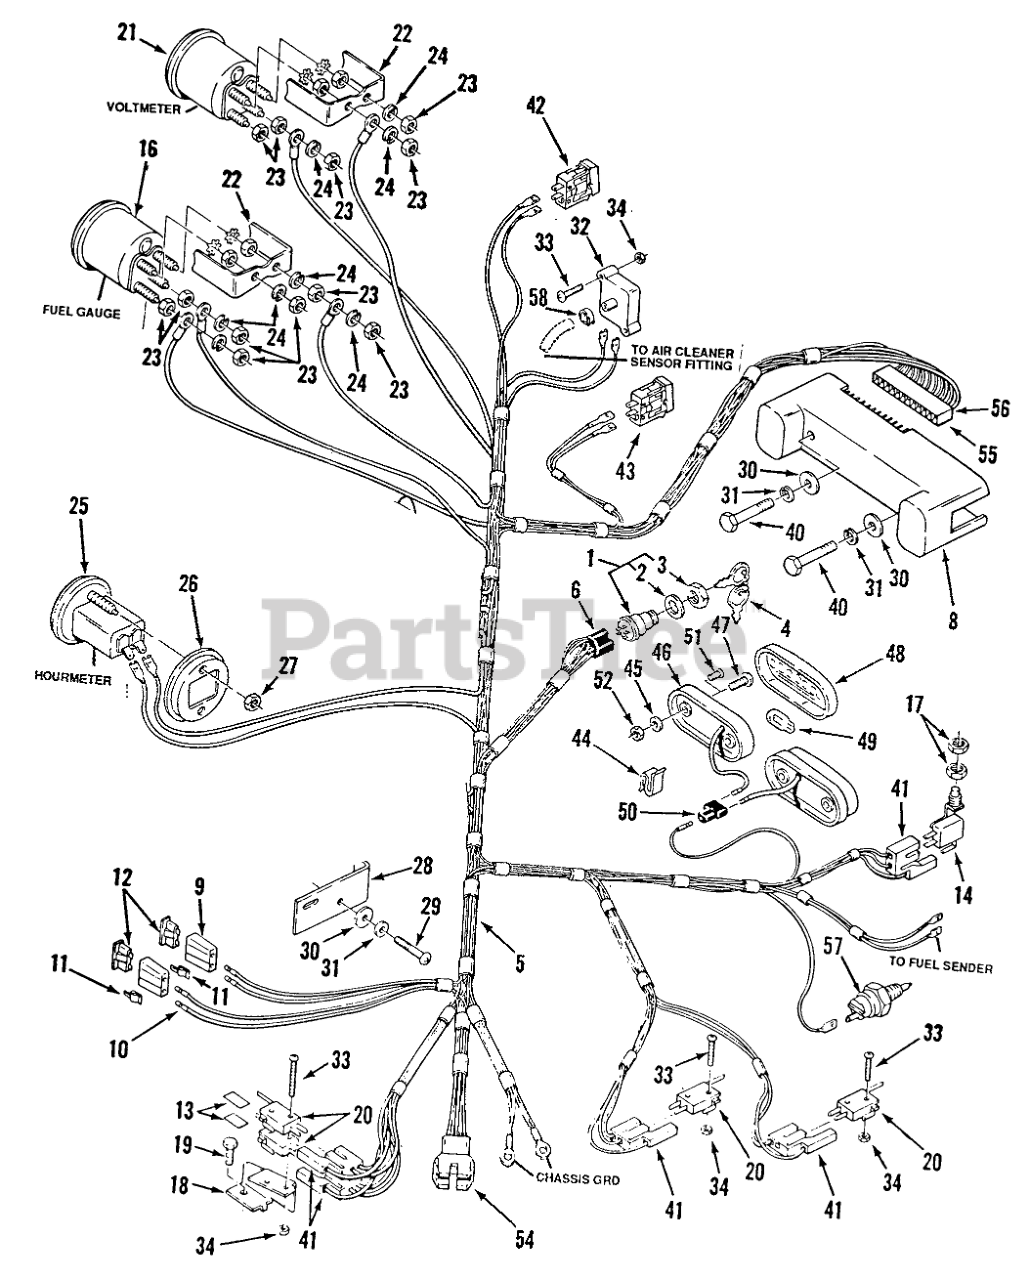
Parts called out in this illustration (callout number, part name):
1	IGNITION SWITCH ASM
2	LOCKWASHER
3	NUT BEZEL
4	Ignition Key
5	WIRING-HARNESS
6	CONNECTOR-5 WAY-SERV
8	6-Light Circuit Module
9	AUTO-FUSEBLOCK TERM
10	TERMINAL FUSE
12	Fuse 10 Amp-ATO or ATC
13	BARRIER - SWITCH
14	Seat Switch
16	Fuel Gauge (includes item 22) All models
17	Special Nut
18	Support-Switch
18	RECEPTACLE TERMINAL
19	Bolt
20	SWITCH
21	Voltmeter (includes item 22)
22	BRKT-GAUGE MOUNTING
23	Nut
24	Lockwasher
25	Hourmeter (includes item 26) 518 & 520-s
26	BRKT-GAUGE MOUNTING
27	Hex Nut
28	Light Bracket 516
29	SCREW-PHCR #8-32X.75
30	WASHER
31	LOCKWASHER
32	SENSOR-AIR CLEANER
33	Screw
34	NUT HEX 4-40 ELAST
40	SCREW
41	CONNECTOR BODY
42	Light Switch
43	SWITCH-TEST
44	SPEED CLIP
45	Lockwasher
46	BASE-TAIL LIGHT
47	Screw
48	LENS-TAIL LIGHT
49	LIGHT BULB
50	CONNECTOR 3 WIRE
51	RIVET-4
52	Nut
53	WASHER
54	9-CIRCUIT CAP
55	Connector-Male
56	Terminal
57	SENSOR-HYDRO OIL HOT
58	Clamp 5/16
59	Wire-Switch to Engine
